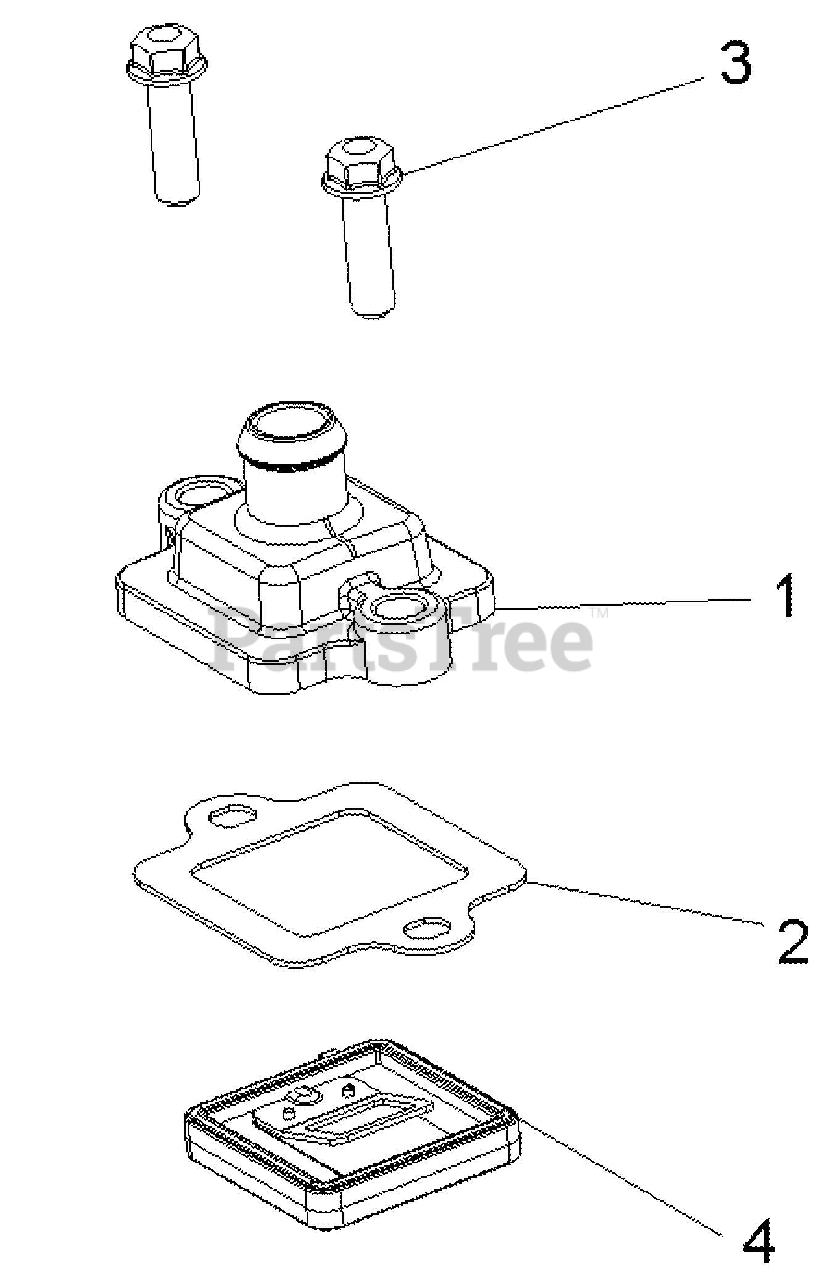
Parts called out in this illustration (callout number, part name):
1	COVER-BREATHER,MACH
2	GASKET-BREATHER,COVER
3	SCR-M6X20,HXFLG,0600214
4	ASM-REED W/GASKET
